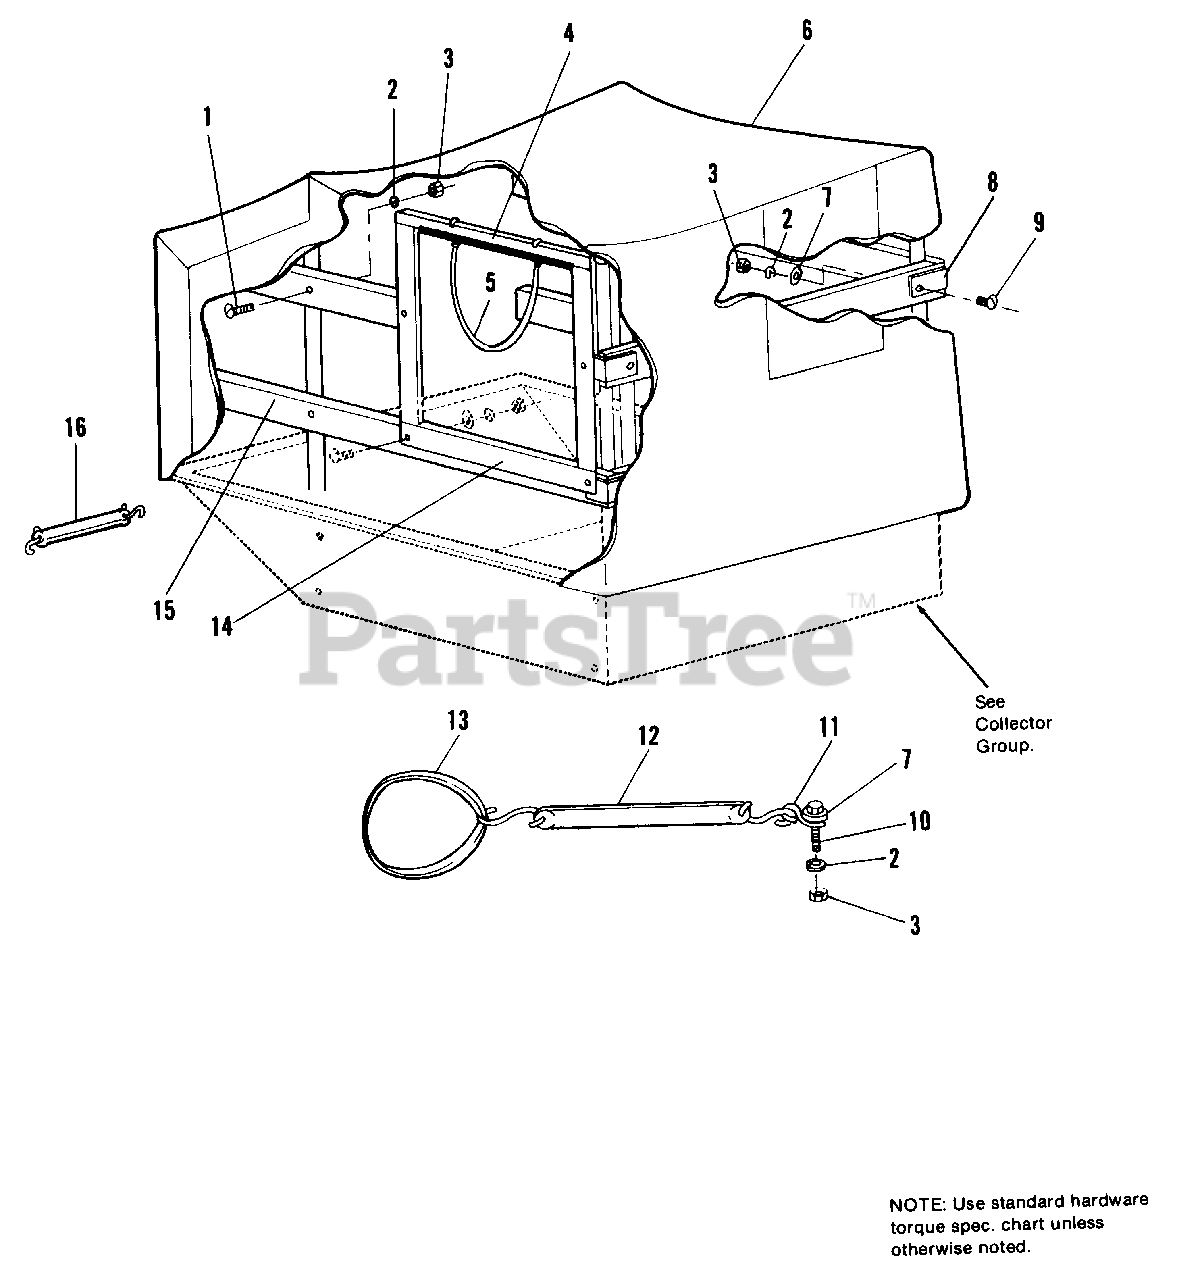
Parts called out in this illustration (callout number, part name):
1	BOLT, Carriage, 5/16-18 x 2, Gr. 2
2	LOCKWASHER, 5/16
3	NUT, Hex, 5/16-18
4	STRIP, Plactic 11"
5	STRETCH CORD (1691094 only)
6	COVER, Cart
7	WASHER, Plain, 5/16
8	"L" Bracket
9	BOLT, Carriage, 5/16-18 x 1-1/4, Gr. 2
10	CAPSCREW, Hex Hd., 5/16-18 x 1, Gr. 5 (1691094 only)
11	"S" HOOK (1691094 only)
12	STRAP, Rubber, 14" (1691094 only)
13	BAND, Rubber (1691094 only)
14	COLLAR, Metal
15	SIDE, Wood (Must be cut to properHOSE, Fuel, Cut to 12th)
16	"S" HOOK STRAP, Rubber 19"
